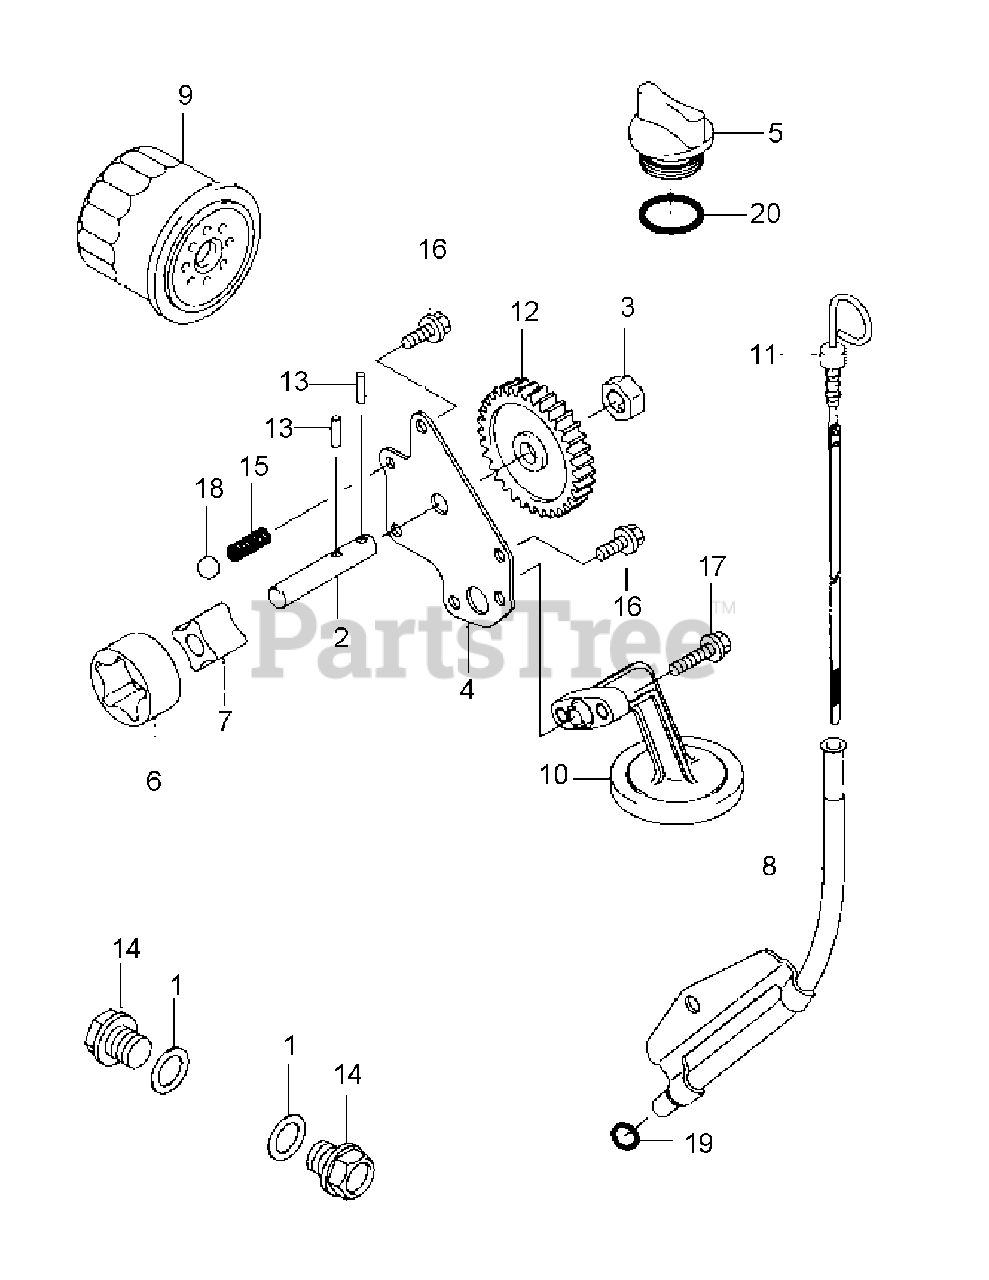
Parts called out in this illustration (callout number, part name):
1	DRAIN PLUG GASKET
2	OIL PUMP SHAFT
3	OIL PUMP HOLDER
4	OIL PUMP COVER
5	OIL FILLER CAP
6	OUTER PUMP ROTOR
7	INNER PUMP ROTOR
8	OIL GAUGE PIPE
9	OIL FILTER
12	SPUR GEAR 33T
16	FLANGED BOLT
17	FLANGED BOLT
19	O-RING 10mm
20	O-RING 25mm
